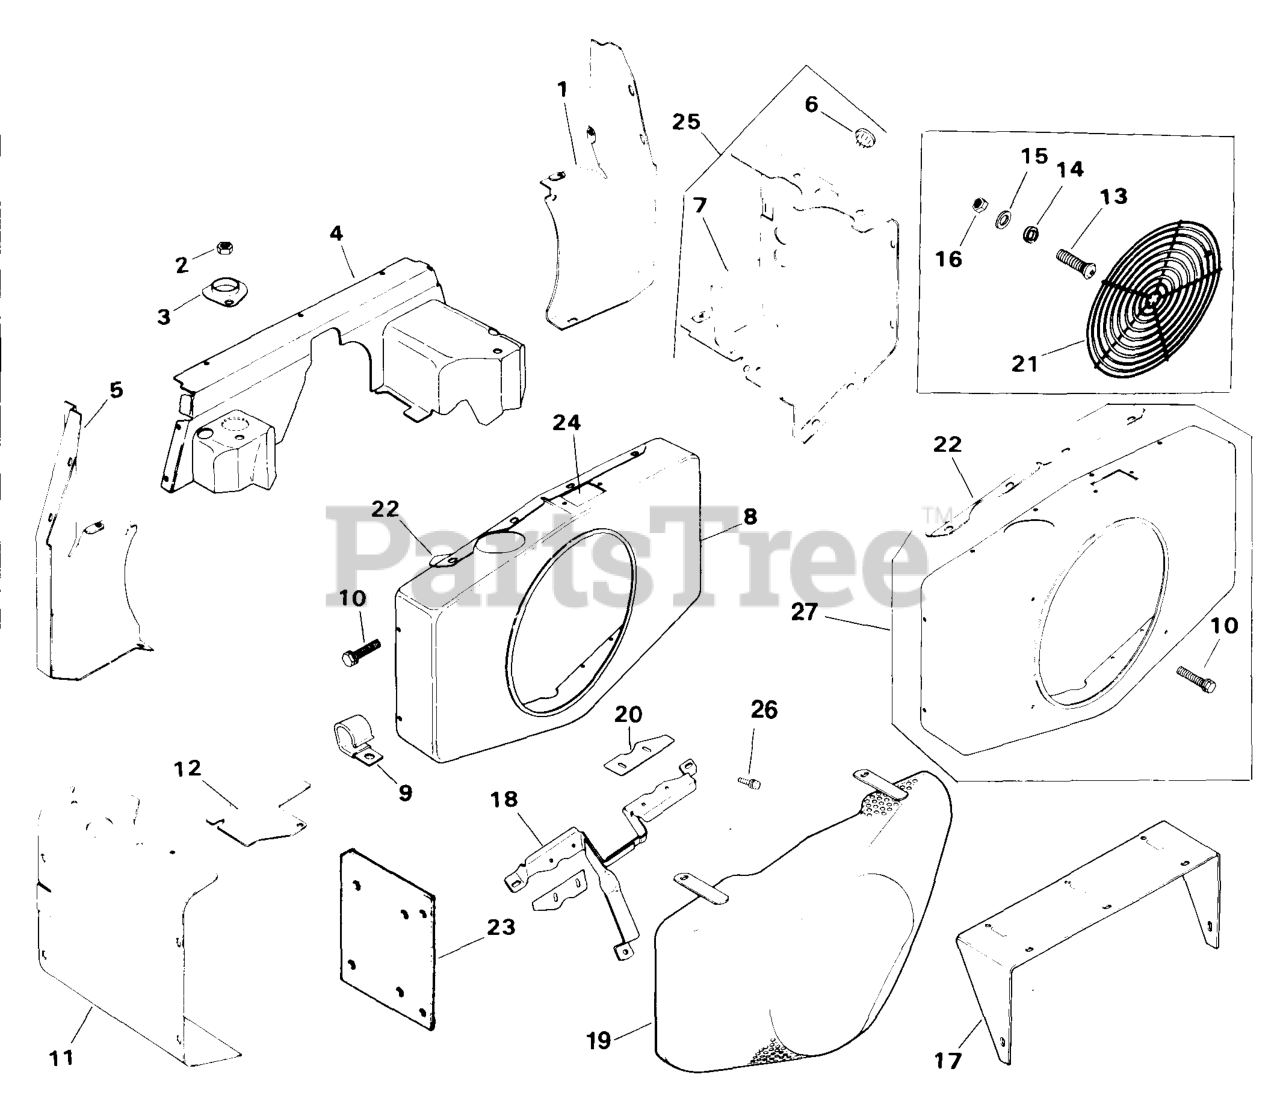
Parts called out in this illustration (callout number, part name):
7	Baffle, #1 Cylinder Head (6-1/8" Wide With 5-1/8" Wide Rear Cylinder Baffle)
10	Screw, Hex. Wash. Hd. 1/4-20x7/16"
11	Baffle, #2 Cylinder Head
12	Baffle, Fuel Pump
13	Screw, Hex. Wash. Hd. 1/4-20x5/8"
14	Washer, Flat
22	Bracket, Upper Housing
27	Kit, Blower Housing
